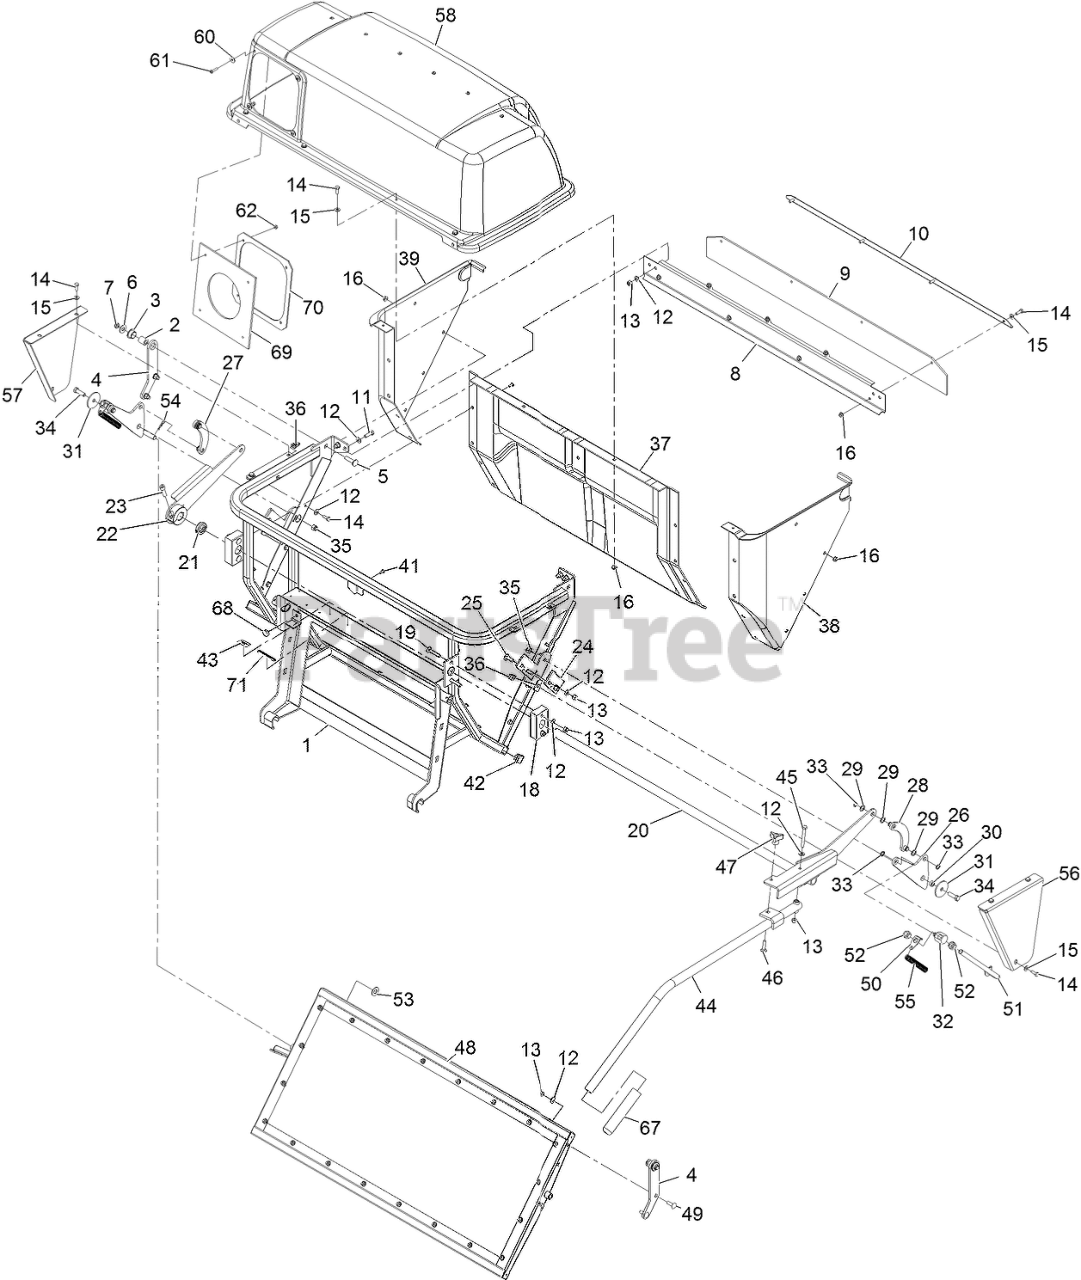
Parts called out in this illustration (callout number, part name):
1	FRAME ASM
2	PIN-PIVOT, HINGE
3	BEARING
4	PLATE-HINGE
5	SCREW-CARR
6	WASHER-FLAT
8	PLATE-REAR
9	SEAL-DOOR
10	STRAP-HOLD DOWN
11	SCREW-HH
12	WASHER-PLAIN
13	NUT-LOCK, NI
14	SCREW-HH
15	WASHER-FLAT
18	BEARING
19	BOLT-CAR
20	BELLCRANK
21	SHAFT-COLLAR
23	SCREW-HSH
24	STOP-LINKAGE
25	BOLT-CARR
26	ARM-LINKAGE, DOOR
27	LINK-RH
28	LINK-LH
29	WASHER-NYLON
30	BEARING-LINKAGE, PIVOT
32	TRUNNION-LINK
33	RING-RETAINING
34	SCREW-HH
35	NUT-LOCK, NI
37	PANEL-BAGGER
38	PANEL-BAGGER, LH
39	PANEL-BAGGER, RH
41	RIVET-BLIND
43	Decal-Patent Ttco.Com
44	HANDLE-QD7
45	SCREW-HH
46	Bolt-Carriage 5/16-18 X 1 1/4
47	KNOB-3 PRONG
48	Asm, Door
49	SCREW-CARR
50	ANCHOR-SPRING
51	LINK-DOOR
52	NUT-HEX
53	WASHER-FLAT
54	PIN-COTTER
58	ASM, HOOD
60	WASHER-FLAT
61	SCREW-PPH
62	NUT-LOCK, NI
67	HANDLE-GRIP
69	SEAL-CHUTE
70	CLAMP-SEAL
71	DECAL-WARNING
